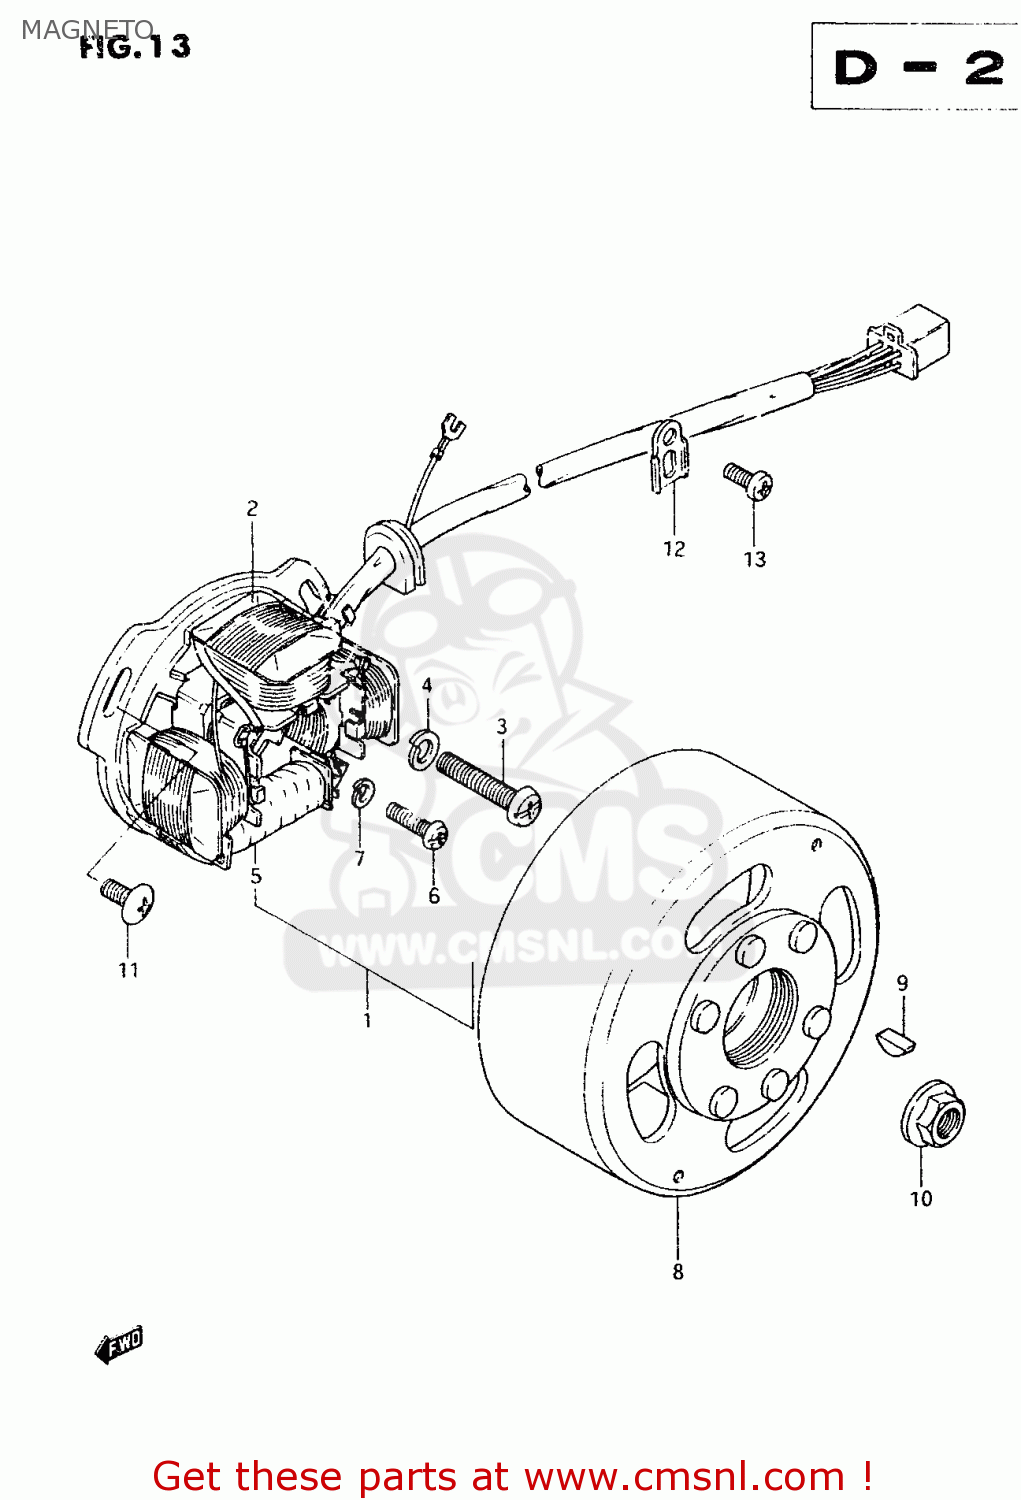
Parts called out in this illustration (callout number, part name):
1	STARTER ASSY
2	COIL,STARTER
3	SCREW
4	WASHER,LOCK
5	COIL,PRIMARY
6	SCREW
7	WASHER,LOCK
8	ROTOR ASSY
9	KEY
10	NUT
11	SCREW
12	CLAMP,GENERATOR LEAD WIRE
13	SCREW
